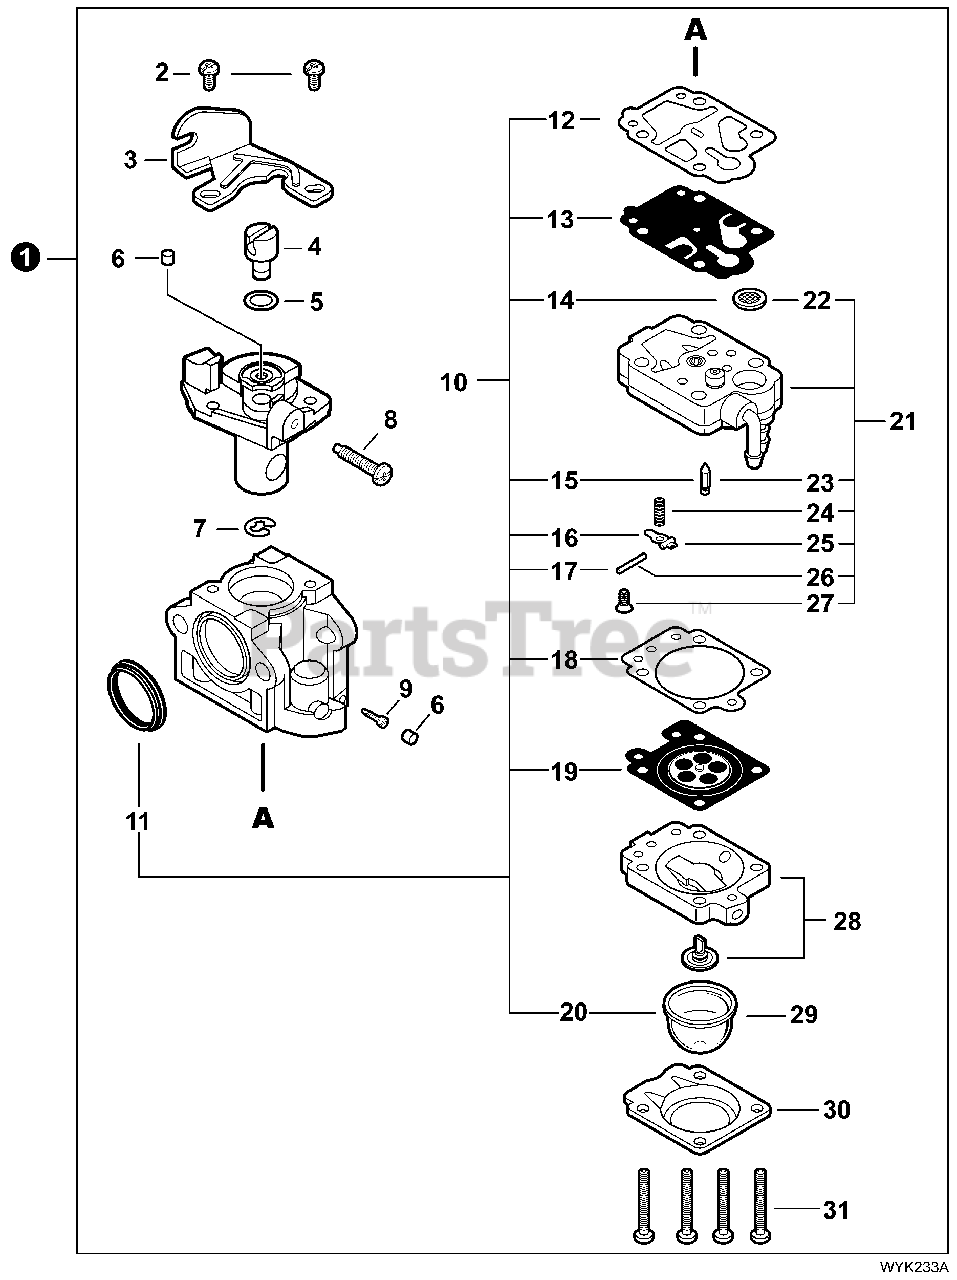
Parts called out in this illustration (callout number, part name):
1	CARBURETOR - WYK-233A
3	BRACKET, THROTTLE CABLE
9	NEEDLE, HIGH SPEED
10	REPAIR KIT, CARBURETOR
11	RING, PACKING
12	GASKET, PUMP
13	DIAPHRAGM, PUMP
14	STRAINER
15	VALVE, INLET NEEDLE
16	LEVER, METERING
17	PIN, METERING LEVER
18	GASKET, DIAPHRAGM
19	DIAPHRAGM, METERING
20	BULB, PURGE
21	BODY ASSY, PUMP
22	STRAINER
23	VALVE, INLET NEEDLE
24	SPRING, METERING LEVER
25	LEVER, METERING
26	PIN, METERING LEVER
28	BODY ASSY, PURGE
29	BULB, PURGE
30	RETAINER, PURGE BULB
